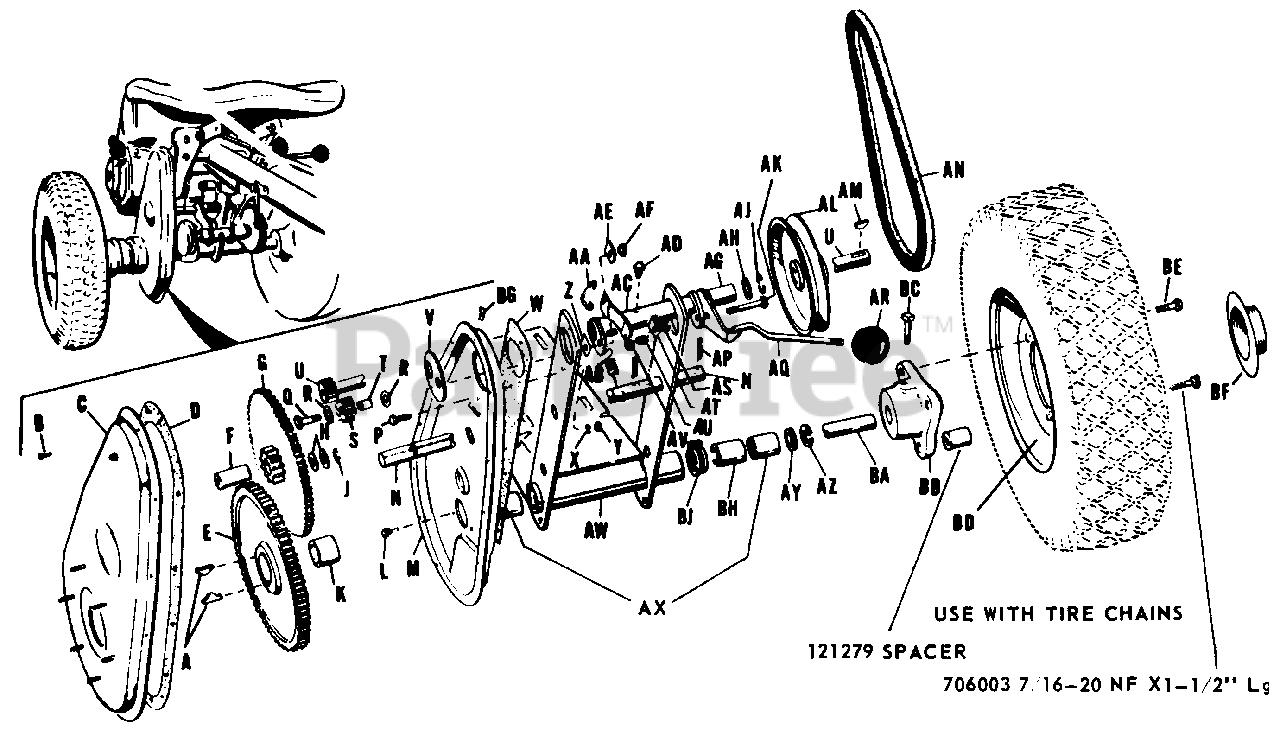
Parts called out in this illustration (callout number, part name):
A	Key, Hi Pro HP-608
B	Screw, Self Tapping #10 x 3/8
C	Cover Assembly, Gear Case
D	Gasket, Gear Case
E	Gear, Drive
F	Bearing, Intermediate Pinion
G	Gear Assembly
J	Ring, Retaining
L	Capscrew, 5/16-18 x 3/8
M	Case, Gear
N	Shaft, Intermediate
P	Capscrew Hex Hd., 3/8-16 x 1
Q	Hex Hd., Bolt
R	Washer, Plain, 5/16
S	Pinion, Reverse
T	Spacer, Pinion
U	Pinion & Pulley Shaft
W	Gasket, Bearing Housing
X	Washer, Lock 3/8
Y	Nut, Full Hex, 3/8-16
AA	Spring, Extension
AB	Spring, Reverse Lever
AC	Housing Assembly, Bearing
AD	Grease Fitting, Alemite #1911
AE	Plate, Lock
AF	Nut, Full Hex
AJ	Ring, Retaining
AK	Capscrew, Hex Hd., 5/16-18 x 1
AL	Pulley, Transmission
AM	Key, Wodruff 3/16 x 3/8
AP	Pin, Cotter 3/16 x 1 1/4
AQ	Lever Assembly, Shift
AS	Nut, Hex Jam, 3/8-16
AT	Plate, Friction
AV	Nut, Lock, 3/8-16
AW	Housing Assembly, Axle
AX	Bearing, Axle
AZ	Ring, Retaining
BA	Axle, Rear
BB	Hub, Wheel, L.H.
BC	Screw, Set, Sq. Hd., 3/8-1 1/4
BD	Wheel, less tire & tube
BF	Hub Cap, Rear
BG	Speed Nut
BH	Cover, Axle House
